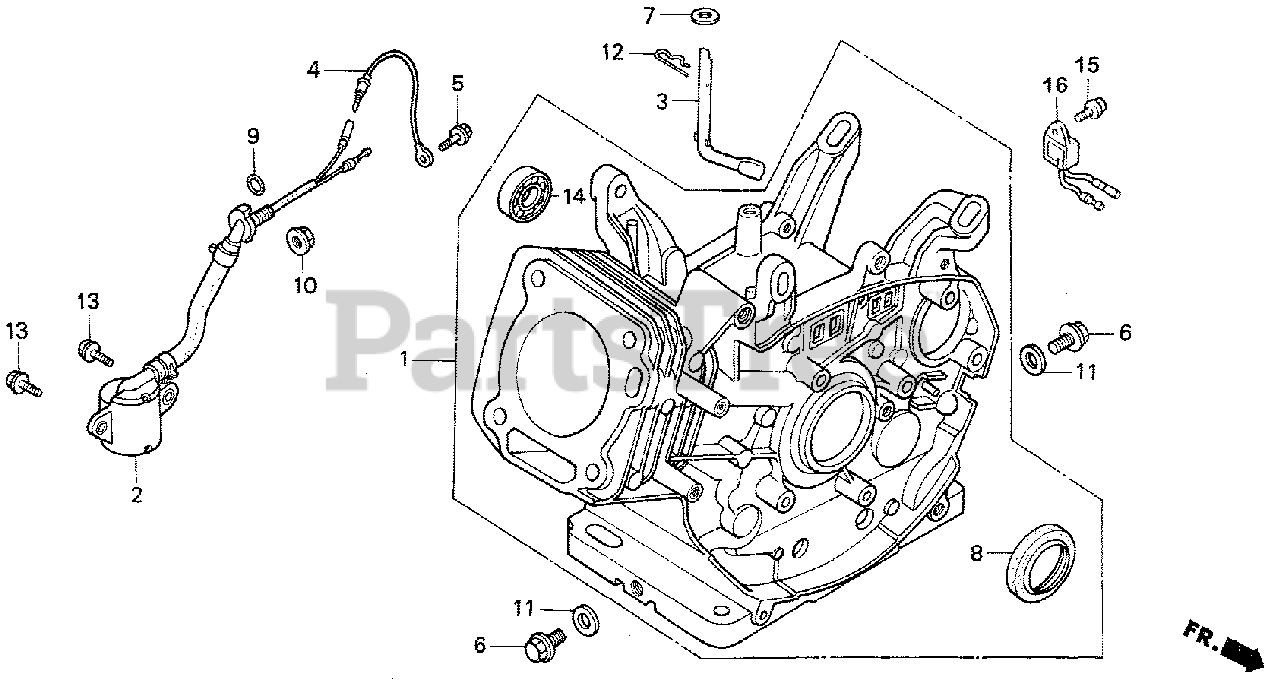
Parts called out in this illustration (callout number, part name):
1	CYLINDER ASSY. (BALANCER+OIL ALERT)
2	SWITCH ASSY., OIL LEVEL
3	SHAFT, GOVERNOR ARM
4	SUB-HARNESS
5	BOLT, FLANGE (6X12) (CT200)
6	BOLT, DRAIN PLUG
7	WASHER (8.2X17X0.8)
8	OIL SEAL (30X46X8)
9	O-RING (13.5X1.5) (ARAI)
10	NUT, FLANGE (10MM)
11	WASHER, DRAIN PLUG (12MM)
12	PIN, LOCK (8MM)
12	PIN, LOCK (10MM)
13	BOLT, FLANGE (6X12)
14	BEARING, RADIAL BALL (6202)
15	BOLT, FLANGE (6X12) (CT200)
16	ALERT UNIT, OIL
